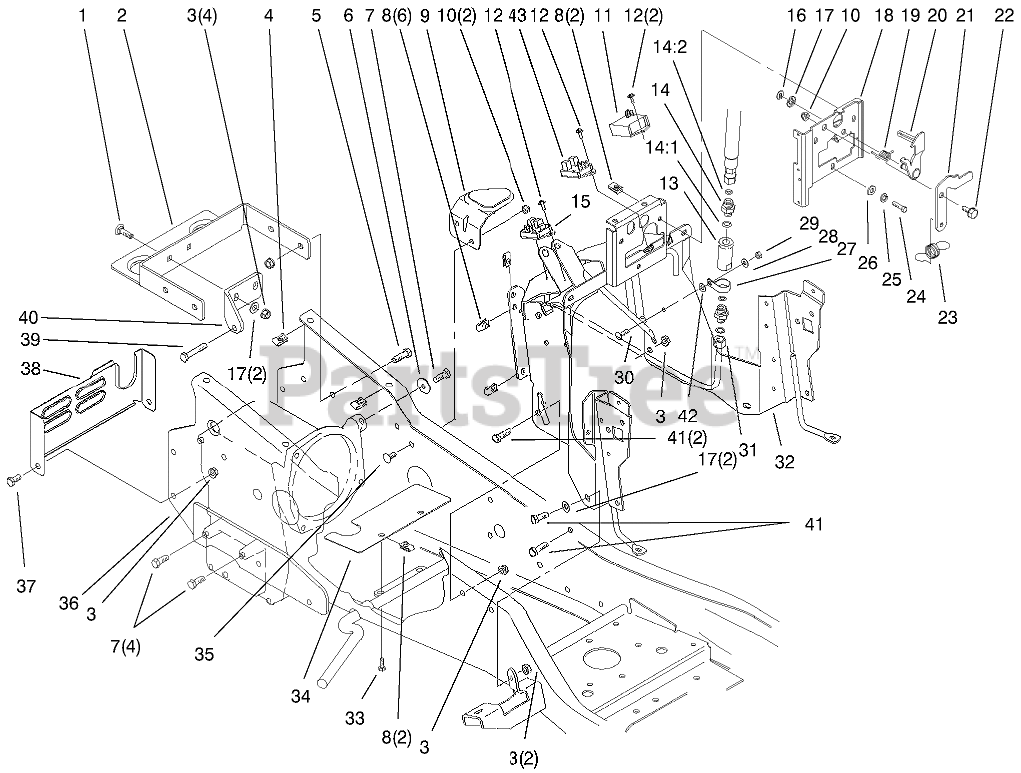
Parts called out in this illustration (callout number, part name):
1	BOLT-CARR
2	Support-Gas Tank
3	NUT-LOCK, NI
4	NUT-U
5	SCREW-HH
6	WASHER
7	SCREW-HH, LOCK
9	SUPPORT-TANK, FUEL
10	NUT-LOCK, NI
11	MODULE-OVER TEMP
12	SCREW
13	FILTER-SCREEN, HYD
14	FITTING-HYD. STRAIGHT
14:1	O-RING
14:2	O-RING
15	MODULE-CRUISE
16	RING-RETAINING
17	WASHER-FLAT
18	BRACKET-LATCH
19	SPRING-LEVER, LATCH
20	LEVER-LATCH
21	LATCH-LEVER, TENSION
22	BOLT-SHOULDER
23	SPRING-LEVER, LATCH
24	SCREW-HH
25	WASHER-LOCK
26	WASHER-FLAT
27	CLAMP-R
28	WASHER-FLAT
29	NUT-LOCK, NI
30	BOLT-CARR
31	TUBE-HYD
32	TOWER ASM
33	SCREW-HH
34	BAFFLE-FAN
35	SCREW-CARR
37	SCREW-HH
38	COVER-REAR
39	SCREW-HH W/LOCTITE
40	Strap-Torque
41	SCREW-HH
42	PUSHNUT-RETAINER, BOLT
43	MODULE-CLUTCH
